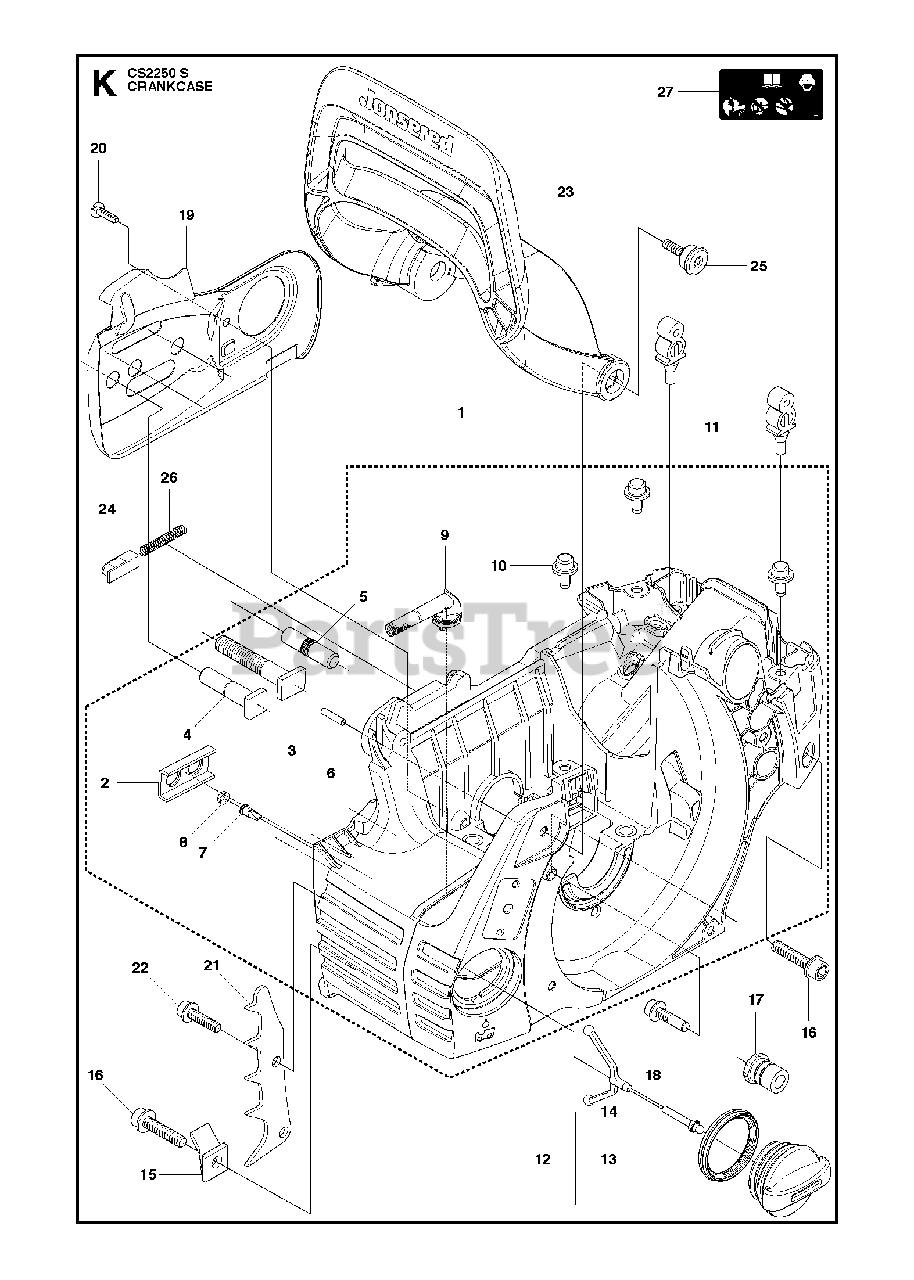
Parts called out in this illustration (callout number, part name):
1	CRANKCASE
2	STIFFENING PLATE
3	BAR BOLT
4	BAR BOLT (X2)
5	BAR BOLT
6	PIN
7	VALVE-CHECK (DUCKBILL)
8	PLUG
9	OIL SCREEN
10	GUIDE PEN
12	TANK CAP ASSY
13	SEALING
14	HOLDER
15	CHAIN CATCHER
16	SCREW IHSCFT
17	LATERAL SUPPORT
19	CHAIN GUIDE PLATE
21	FELLING DOG
23	HAND GUARD
26	LOCK SPRING
